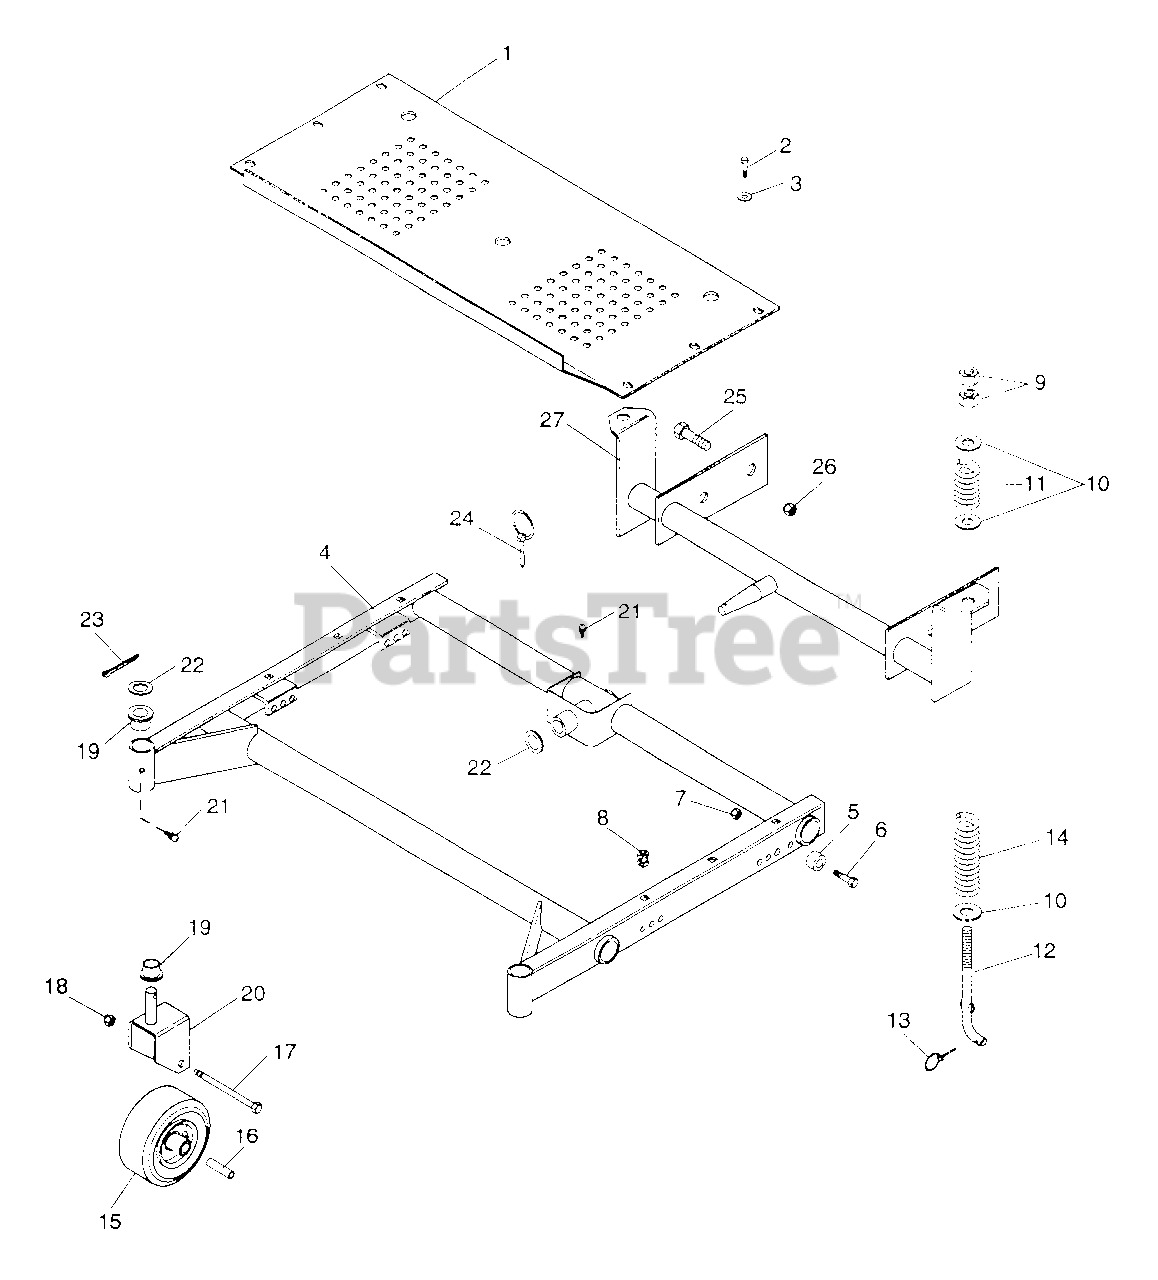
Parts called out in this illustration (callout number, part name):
1	Footboard
2	Screw, Machine .25-20 Pan Head
3	Washer-Flat-Steel .281 x .625 x .065
4	Weldment, Mower Frame 40" 3 Spindle
5	Bushing, 021076 W/E - Coat Finish
6	Bolt-Hex .38-16 x 1.50 Pl Gr. 5
7	Nut-Lock-Nylon .375 - 16 Pl
8	Clip, U - Type Easton #C17453-1420
9	Nut, .50-13 Pl
10	Washer-Flat Steel .531 x 1.062 x .095
11	Spring-Compression .188 x 1.66 x 2.0
12	Rod, Height Adjustment
13	Pin Klik 1.00 x .188 x 1.25
14	Spring, Compression .095 x .75 x 6.25 Wld 35
15	Wheel, Gage 11 x 4 - 4
16	Bushing, Caster Fork
17	Bolt-Hex .50-13 x 6.50
18	Nut-Lock-Nylon .50 - 13 Pl
19	Bushing-Flange 1.020 x 1.75 x .75 Nylon
20	Weldment, Caster Fork
21	Fitting, Lube; .25-28 Self-Thread
22	Bearing-R-thrust 1.002 x 1.552 x .030
23	Pin-Cotter .12 x 1.25 Pl
24	Pin-Klik .25 x 1.75
25	Bolt-Hex .625 - 11 x 1.50
26	Nut, Lock 5/8-11 Hex W/Insr
27	Weldment, Mower Frame Mounting
